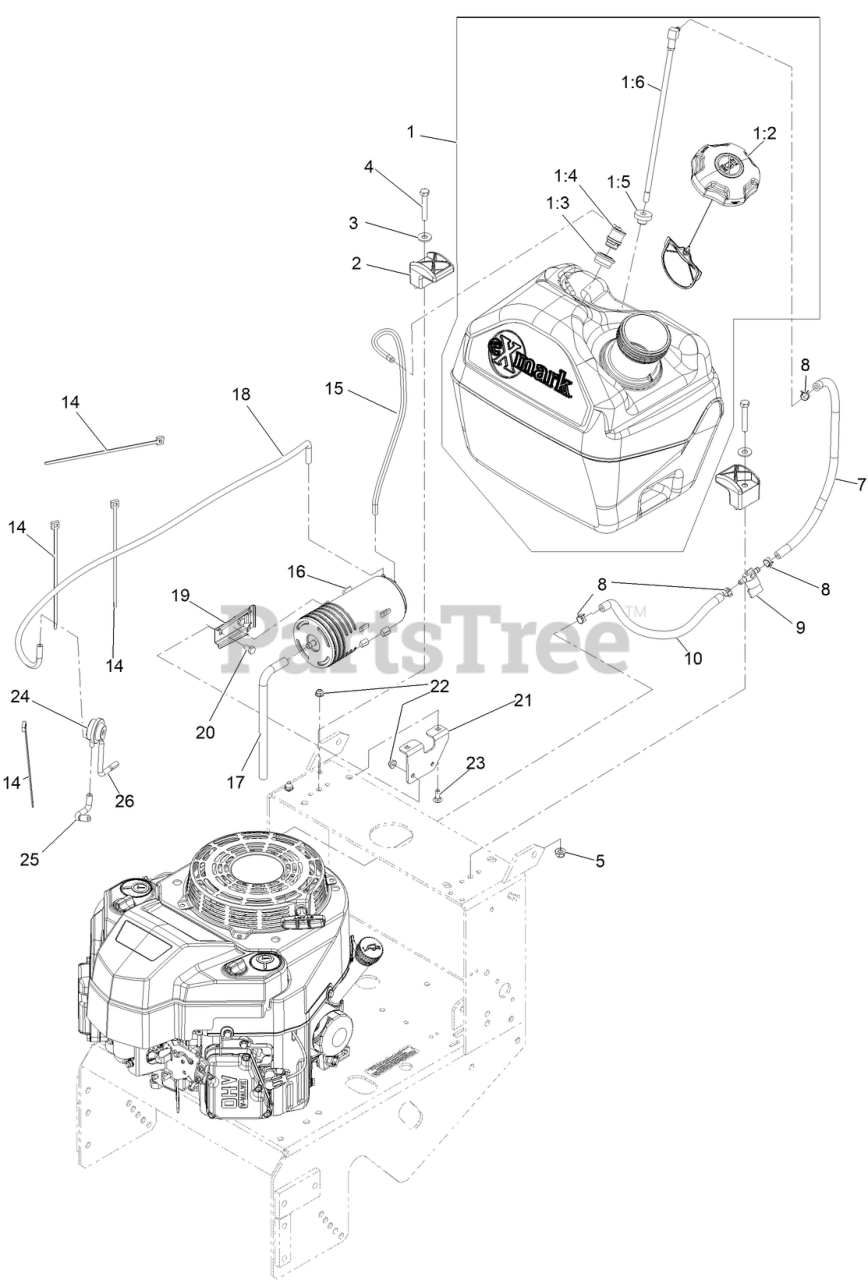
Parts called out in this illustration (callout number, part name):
1	ASM, FUEL TANK 5 GAL
1:2	CAP-FUEL, RATCHETING
1:3	GROMMET
1:4	VALVE-VENT, FUEL
1:5	BUSHING
1:6	FITTING, FUEL W/LINE AND SCREEN
3	WASHER-FLAT
4	SCREW-HH
5	NUT-HF, NI
7	HOSE-FUEL
8	CLAMP-HOSE
9	VALVE-FUEL
10	HOSE-FUEL
14	TIE-CABLE
15	HOSE-VENT
16	CANISTER-CARBON, 800CC
17	HOSE-VENT, CANISTER
18	HOSE-VENT, FORMED
19	BRACKET-CANISTER, CARBON
20	SCREW-HH
21	BRACKET-CANISTER, CARBON
23	BOLT-CARR
24	VALVE-CONTROL, VACUUM
25	HOSE-VENT, FORMED
26	HOSE-VENT, FORMED
